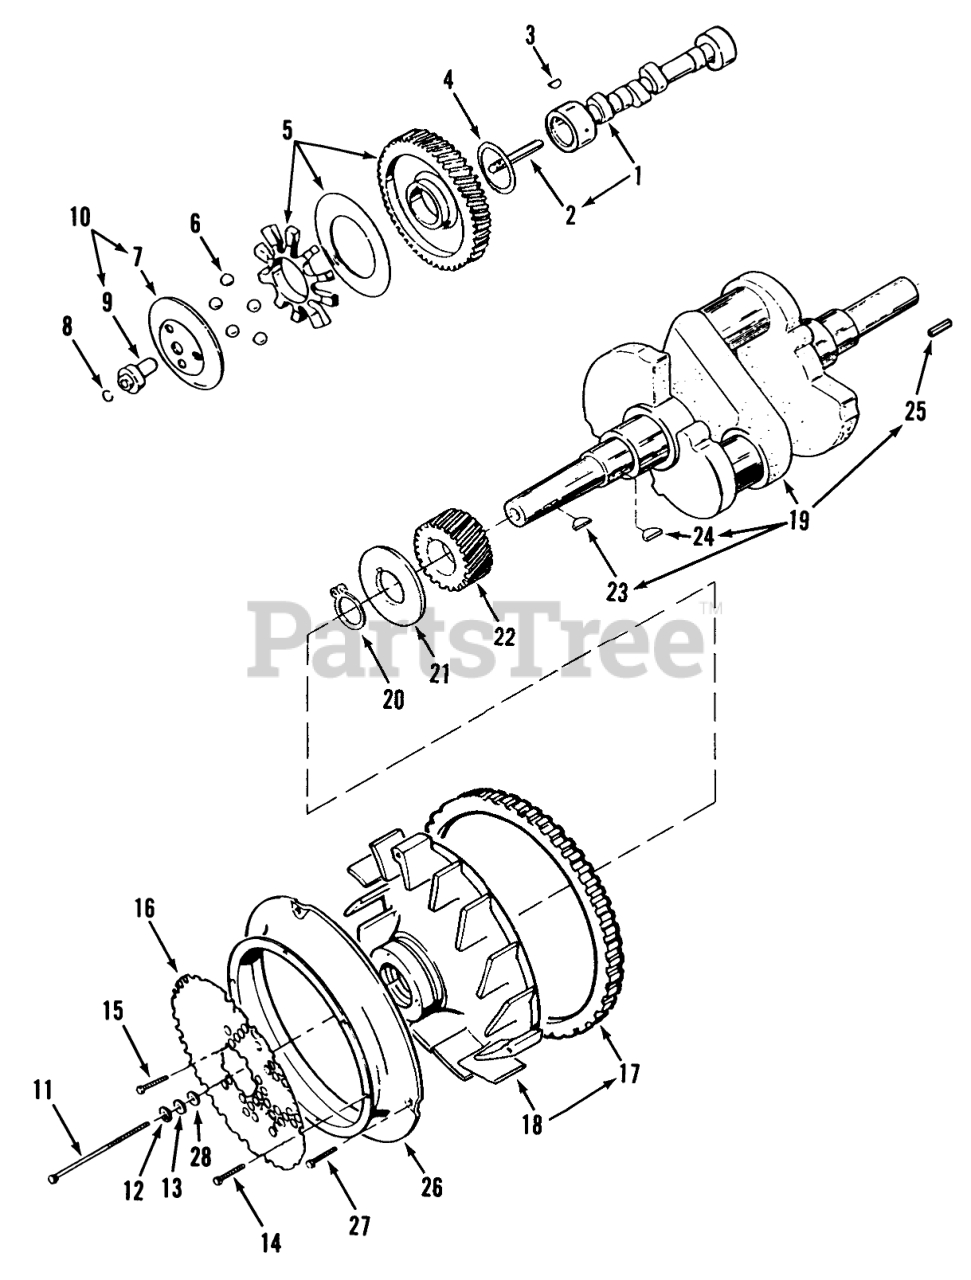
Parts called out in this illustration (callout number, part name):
1	Camshaft (Includes Center Pin)
2	Pin
3	Key
4	Washer
5	Camshaft Gear (Includes Plate and Spacer)
6	Ball
7	Cup-Governor
8	Retaining Ring
9	Governor Cup Hub
10	Governor Cup Kit (Includes Cup and Hub)
11	Screw
12	SPRING LOCKWASHER
13	Washer
14	HWH S.T. SCREW
15	Locking Bolt
16	FLYWHEEL GUARD
17	Gear-Ring
18	Flywheel (Includes Ring Gear)
19	Crankshaft (Includes Keys)
20	Retaining Ring
21	Washer
22	Gear
23	Key
24	Key
25	Key
26	Blower Wheel Venturi
27	Wash. Hd. Screw 1/4-20 x 1/2
28	SPACER
